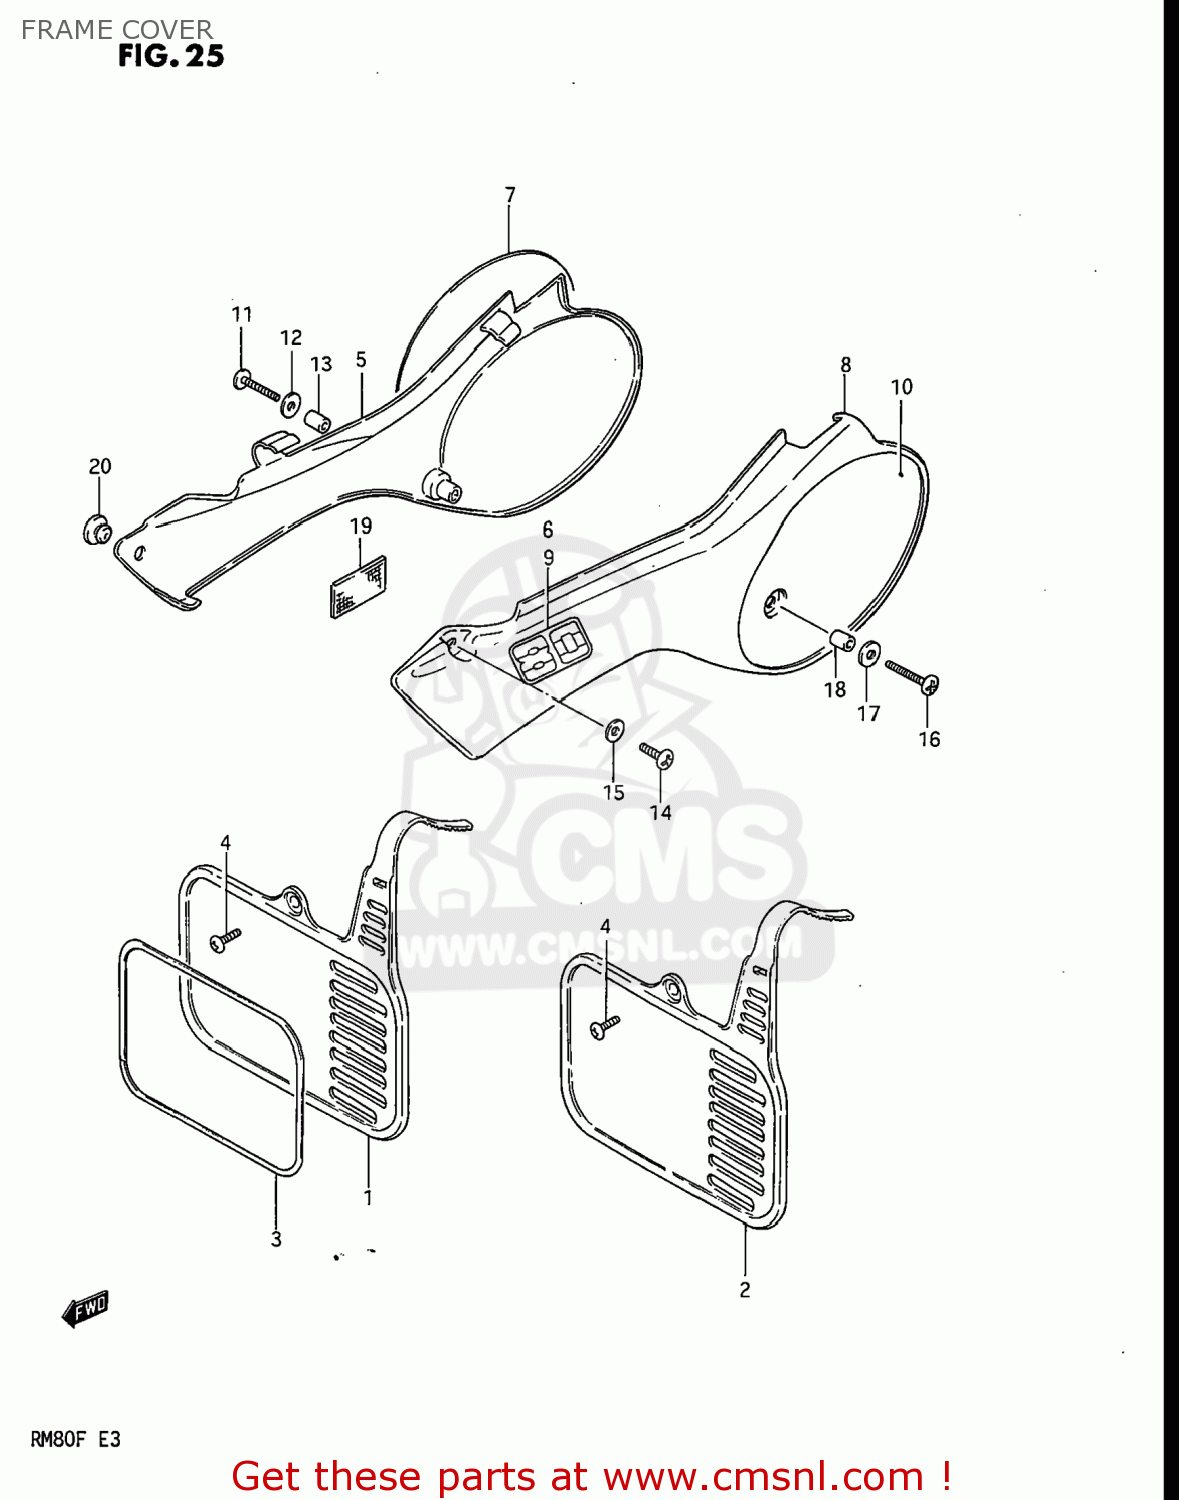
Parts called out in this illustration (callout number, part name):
1	PLATE,FR NUMBER
2	PLATE,NUMBER,FRONT
3	TAPE SET,FRONT NUMBER PLATE
4	SCREW M5X12 DIN 7985/N
5	COVER,FRAME,RIGHT
6	EMBLEM (80)
7	EMBLEM,FRAME COVER,RIGHT
8	COVER,FRAME,LEFT
9	EMBLEM (80)
10	EMBLEM,FRAME COVER
11	SCREW
12	WASHER (6.5X18X1.6)
13	SPACER(6.8X10X24.2)
14	SCREW
15	WASHER
16	SCREW
17	WASHER (6.5X18X1.6)
18	SPACER (6.4X9X20)
19	HEAT SHIELD,FRAME COVER
20	CUSHION
